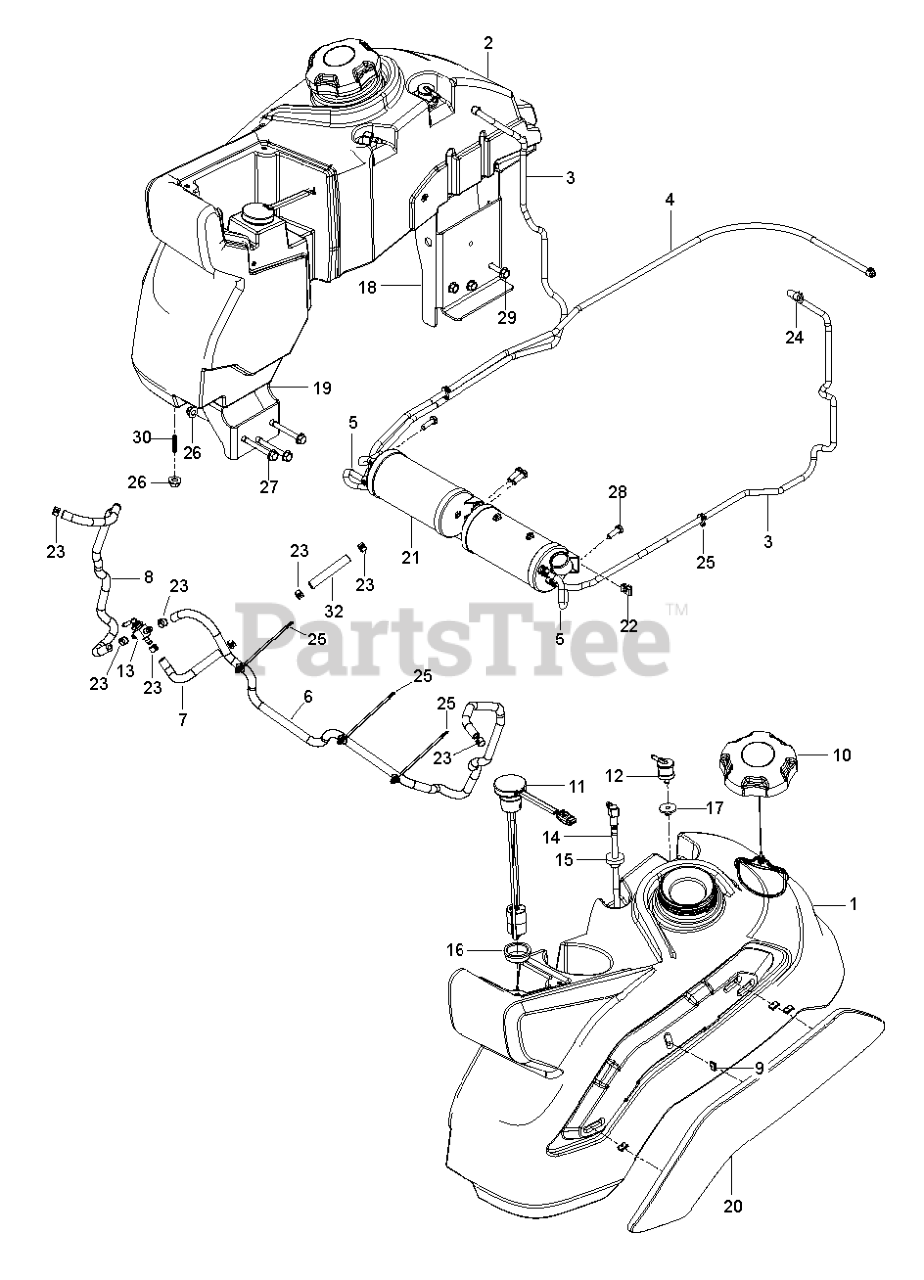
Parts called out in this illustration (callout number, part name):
1	FUEL.TANK.ASM.LH.PZ.REFRESH.18
2	FUEL.TANK.ASM.RH.PZ.REFRESH.18
3	HOSE.3/16".VAPOR.LINE.38"LGTH
5	HOSE 3/16" VAPOR LINE 13" LENG
6	HOSE.1/4".LOW.PERM.FUEL.LN.46"
7	HOSE.1/4".LOW.PERM.FUEL.LN.8"
8	HOSE.1/4".LOW.PERM.FUEL.LN.24"
9	TEE, FUEL LINE 3/16"
10	CAP, FUEL
11	SENSOR.FUEL.LVL.FLOAT.V500
12	VALVE.FUEL.CHECK
13	FUEL VALVE
14	TUBE.ASM.FUEL.TANK.PICK-UP.LH
15	BUSHING OUTLET T
16	GROMMET, FUEL SENSOR
17	GROMMET.CHECK.FUEL
18	BRACKET.FUEL.TANK.REAR.SUP.431
19	BRACKET.FUEL.TANK.REAR.SUP.431
20	COVER.LH.FUEL.TANK/CONSOLE APP
21	CANISTER.FLEX.6.3GAL3/16".TANK
22	1/4-20 U NUT
23	HOSE CLAMP
24	CLAMP, HOSE
25	TIE WRAP, 8-3/8", W/CLIP
26	5/16-18 NYLOC FLANGE NUT
27	BOLT HEX FLGHD 5/16-18X3 GR. 5
28	BOLT
29	SCREW
30	SCREW.5/16-18X1.25"THREADED
32	HOSE.1/4".LOW.PERM.FUEL.LN.3"
